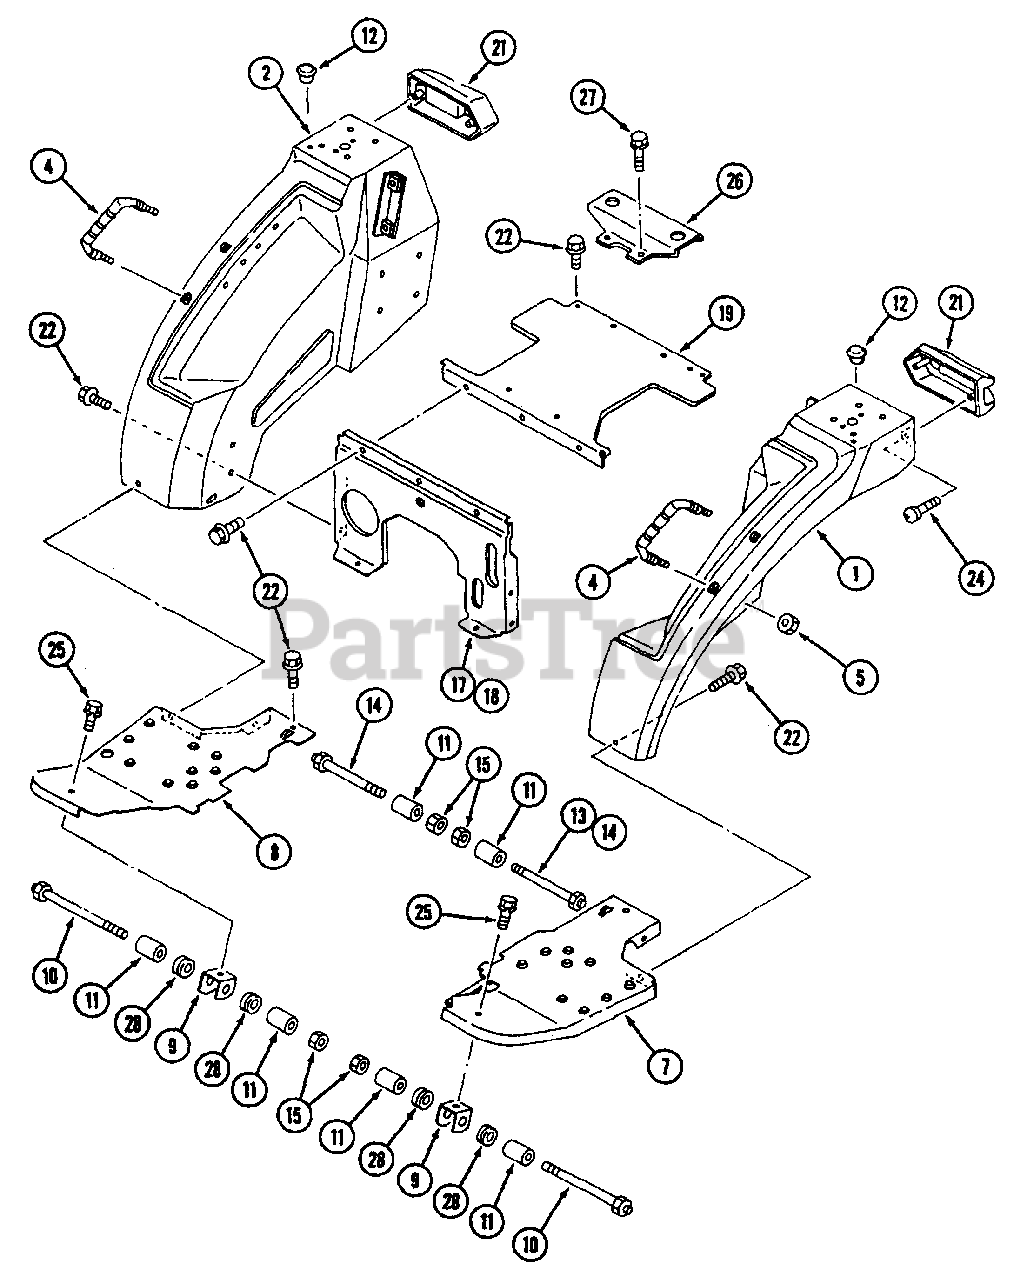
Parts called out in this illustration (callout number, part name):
17	Cover, Front (not used on this product)
27	Bolt (Used with MA-19632401AG0 hydraulic case)
27	Bolt (Used with MA-19632401AG1 hydraulic case)
